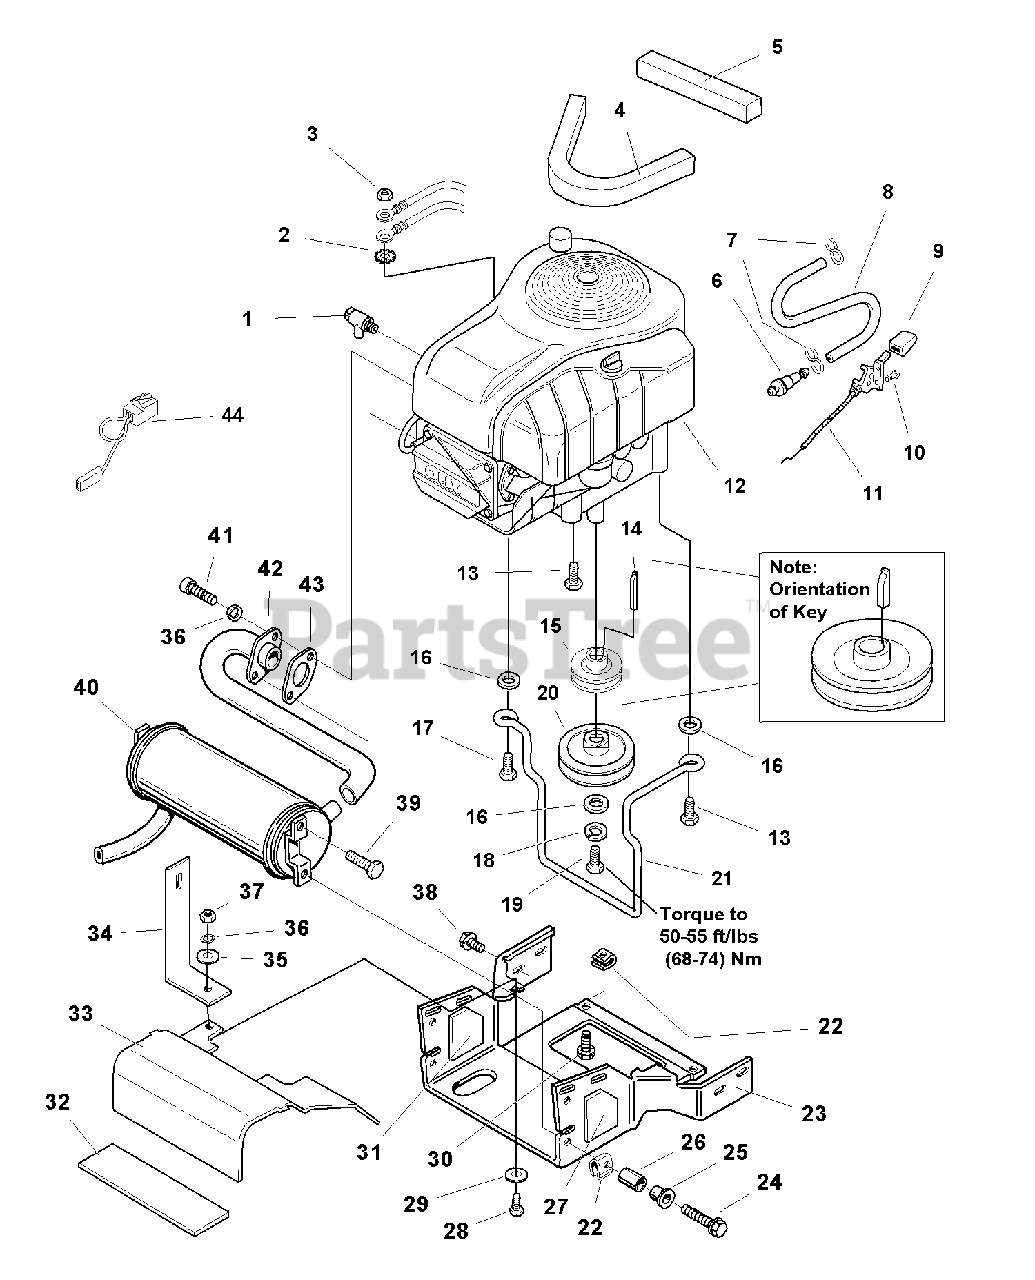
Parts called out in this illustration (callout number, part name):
1	VALVE-SHUT OFF
2	LOCKWASHER, External Tooth 3/8
3	NUT, Hex 3/8-16
4	SEAL, Foam
6	FILTER, Fuel
7	CLAMP, Hose Type E
8	HOSE, 12" Long
10	CAPSCREW, Hex Washer Head 1/4-14 x 5/8
11	CABLE, Throttle Control, 14~ Long
12	ENGINE-15/16/17HP Briggs & Stratton INTEK SINGLE
13	CAPSCREW, Hex Washer Head, Taptite, 3/8-16 x 1-1/2
14	KEY, Hi-Pro
15	PULLEY, Hydro Only
15	PULLEY, Gear Only
16	WASHER
17	CAPSCREW, Hex Washer Head, Taptite, 3/8-16 x 2
18	LOCKWASHER, 7/16
19	CAPSCREW, 7/16-20 x 2
20	PULLEY, 5.40 O.D.
22	NUT, Speed 5/16-18
23	DUCT, Muffler
24	CAPSCREW, Hex Flange Lock, 5/16-18 x 1-1/4
27	INSULATION, LH
28	CAPSCREW, 5/16-18 X 1
29	WASHER
30	CAPSCREW, Hex Flange Lock, 5/16-18 x 3/4
31	INSULATION, RH
33	DUCT, Muffler, Upper
34	STRAP, Torque
36	LOCKWASHER, 5/16
37	NUT, Hex 5/16-18
38	CAPSCREW, Hex Washer Head, Taptite, 5/16-18 x 1/2
39	CAPSCREW, Hex Washer Head, Taptite, 1/4-20 x 3/8
41	CAPSCREW, 5/16-18 x 3/4, G8
42	PIPE, Exhaust
44	WIRE ASSEMBLY, B&S (CE Models)
